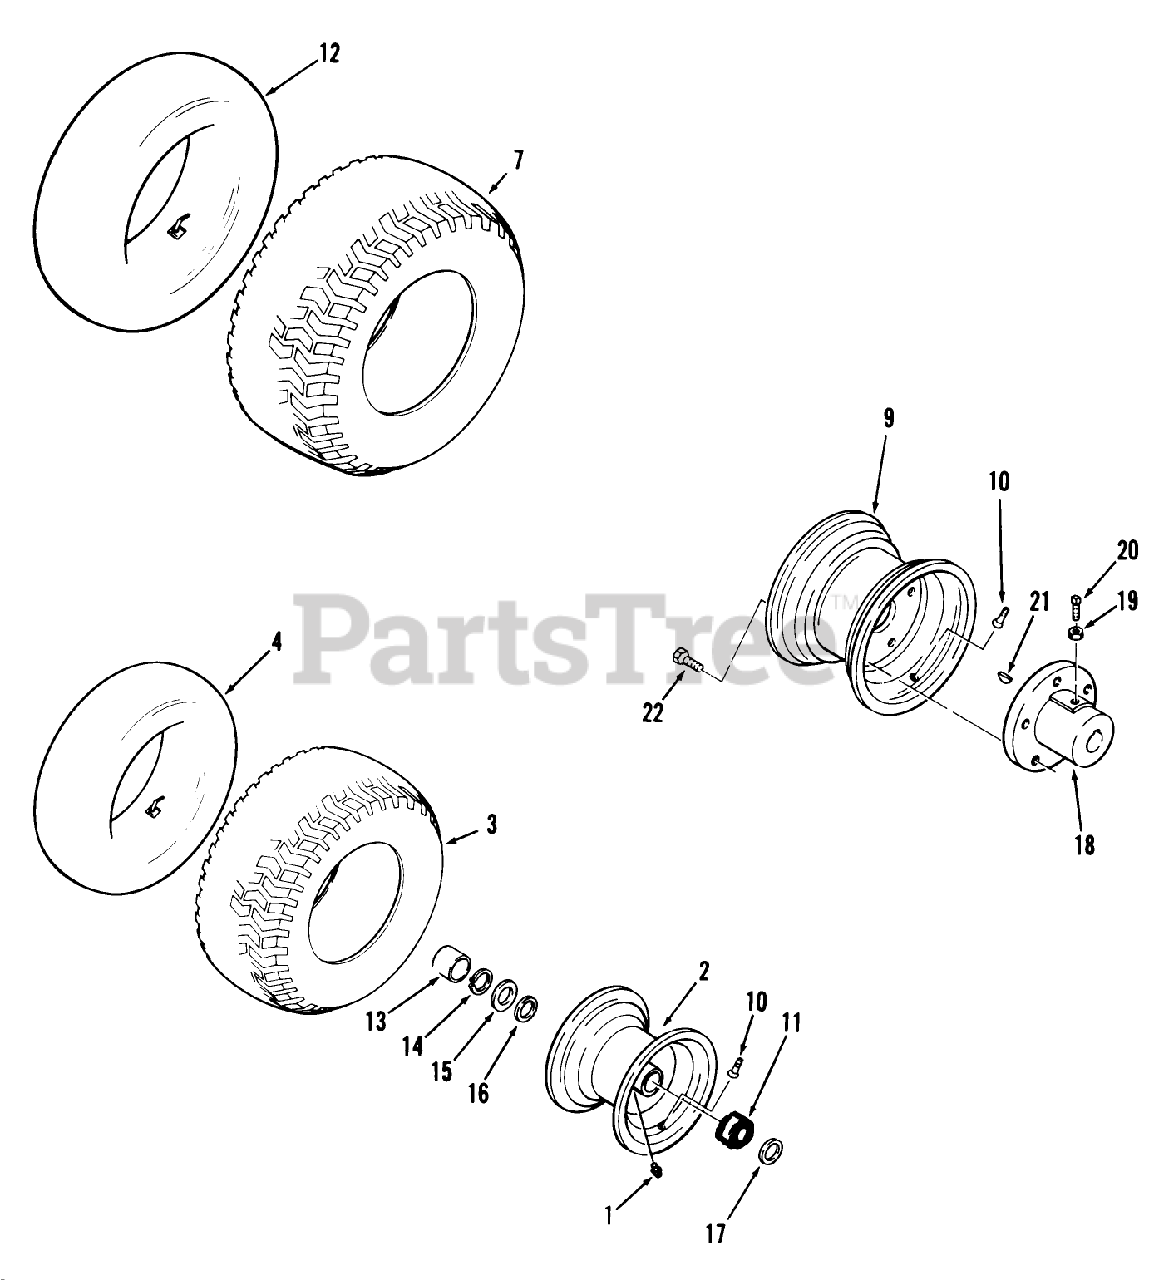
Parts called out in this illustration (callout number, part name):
10	VALVE
11	BEARING-RADIAL FLNGE
16	WASHER
17	WASHER-SHIM
21	KEY-WOODRUFF
